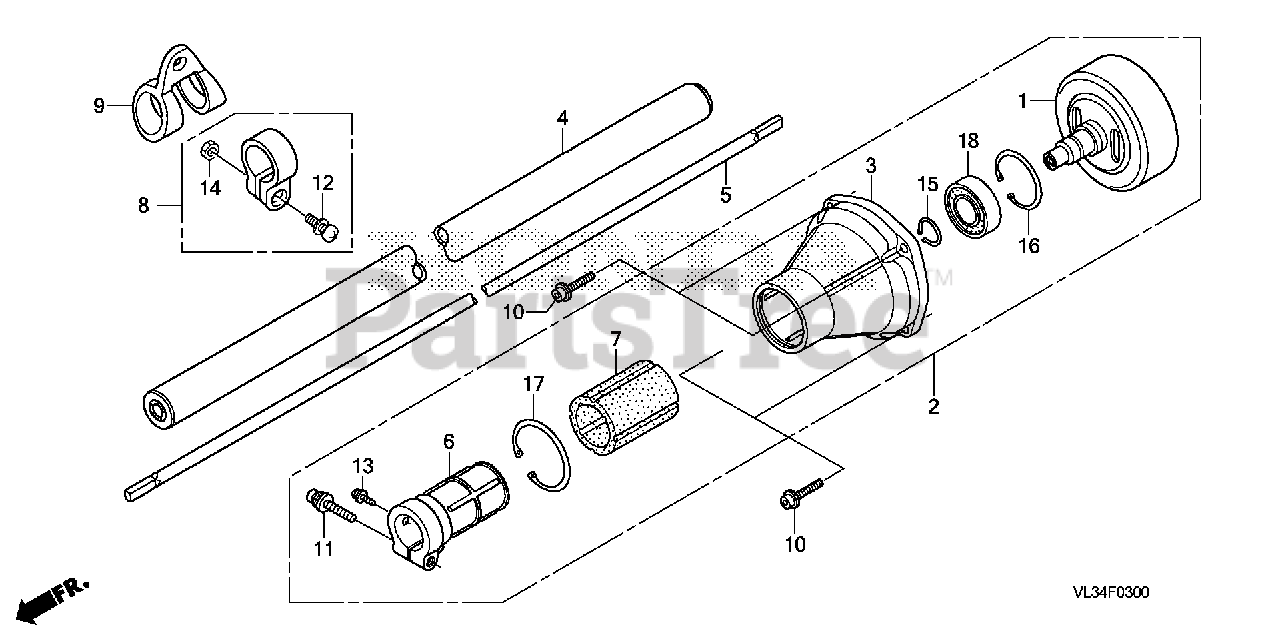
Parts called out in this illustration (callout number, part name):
1	CLUTCH OUTER
2	HOUSING ASSY., CLUTCH
3	HOUSING, CLUTCH (A)
4	PIPE ASSY., FRAME
5	SHAFT, DRIVE
6	BRACKET, ENGINE MOUNTING
7	RUBBER, ENGINE MOUNTING
8	HOLDER A, HANGER
9	HOLDER B, HANGER
10	BOLT, FLANGE SOCKET (6X20)
11	BOLT, SOCKET (6X30)
12	SCREW-WASHER (5X25)
13	SCREW-WASHER (5X10) (NOT AVAILABLE)
14	NUT, HEX. (5MM)
15	CIRCLIP (OUTER) (15MM)
16	CIRCLIP (INNER) (35MM)
17	CIRCLIP (INNER) (45MM)
18	BEARING, RADIAL BALL (6202)
